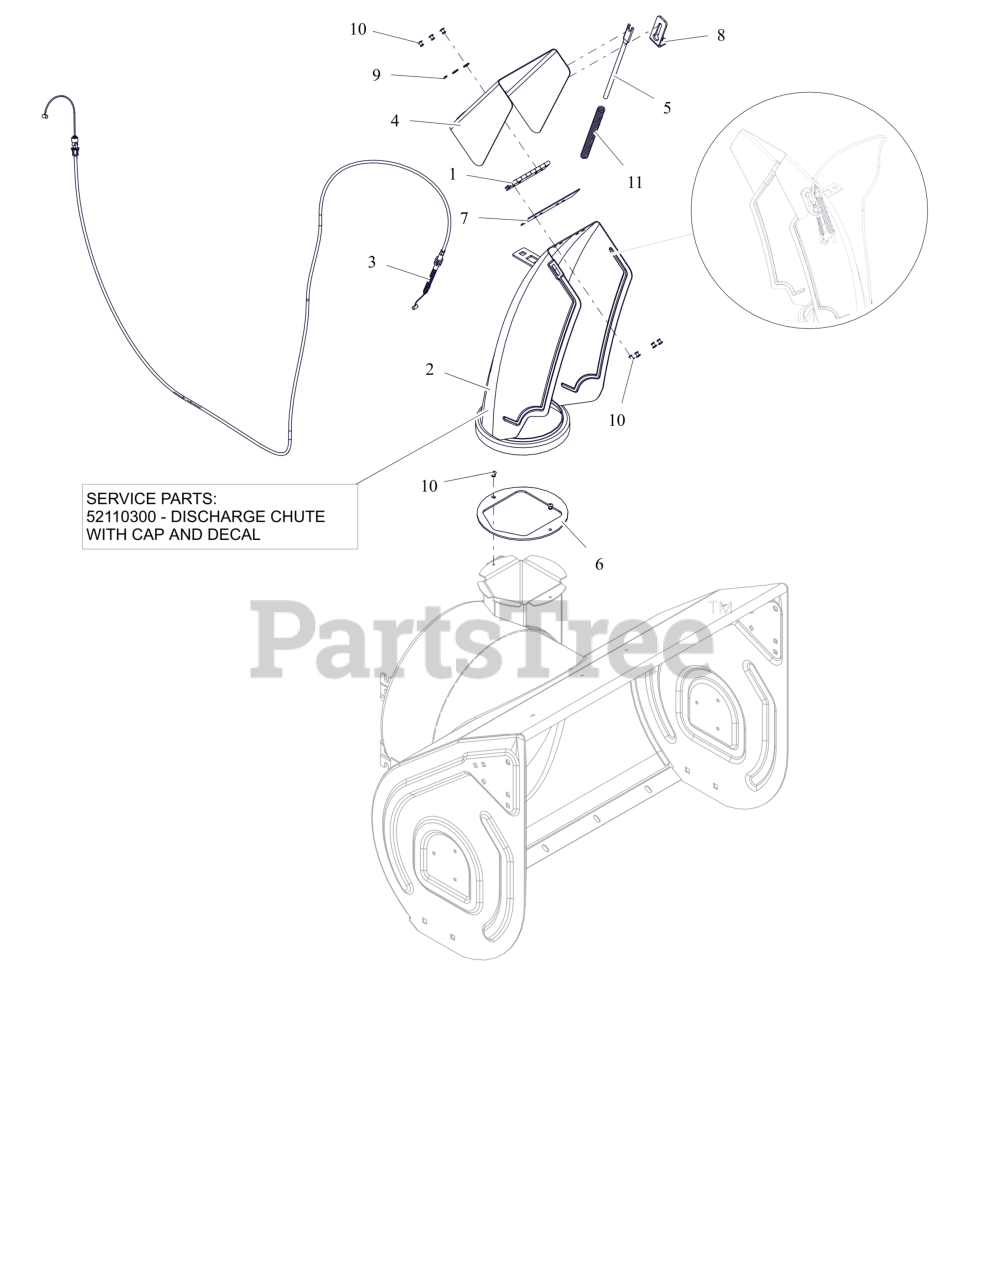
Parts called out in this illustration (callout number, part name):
2	CHUTE,DISCHARGE,RMT,ID
2	CHUTE, DISCHARGE W/CAP
3	CABLE, E-CHUTE CAP
4	CAP, LARGE REMOTE W/DECAL
5	ROD, DEFLECTOR CAP
6	BAFFLE, DISCHARGE NECK
7	CAP SEAL 5.50
8	BRACKET, ANCHOR-CHUTE CABLE
9	WSHR,FLT .196X.500X.066 ZCC
10	RVT, POP .1875 ZCC
11	SG-COMP .08X.40X6.50 14#/IN
